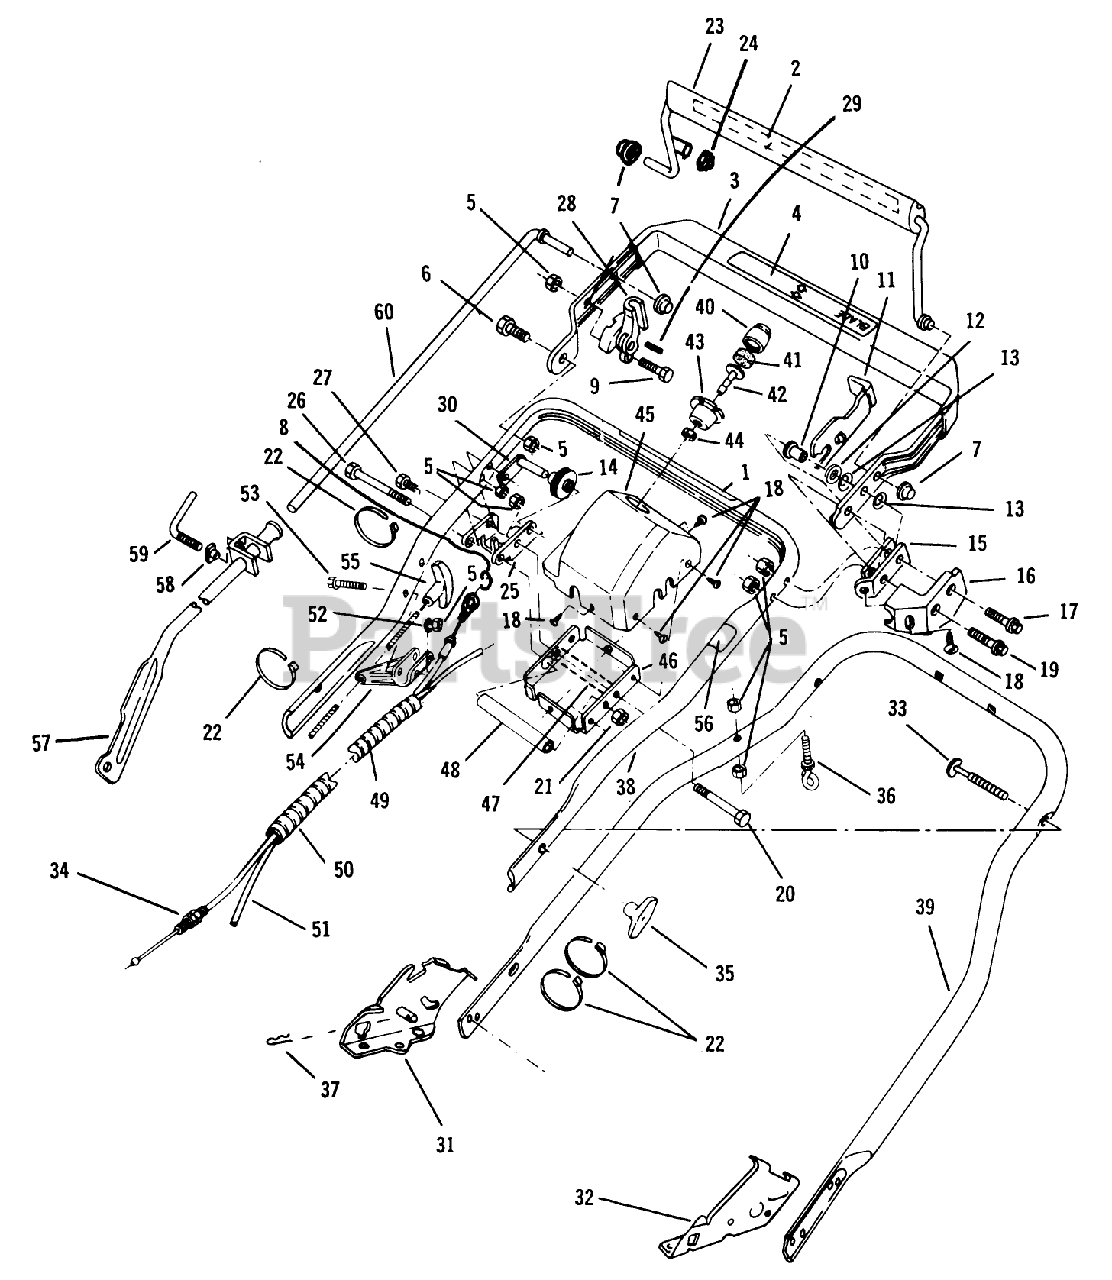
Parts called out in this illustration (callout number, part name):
3	Top Handle and Grip Assembly
5	LOCKNUT E
6	BOLT
8	RET. RING
10	SPACER
12	WASHER M
15	DOWN STOP
16	LOCKOUT GUARD
17	BOLT SHOU
18	SCREW F
19	SCREW
24	NUT ACORN
26	BOLT-CONSOLE
31	BRACKET ASM - HANDLE, SP, RH
32	BRACKET ASM - HANDLE, SP, LH
33	BOLT QUALITY
34	CONTROL CABLE
35	NUT-WING
36	EYE BOLT WAS MFG
37	HAIR PIN
41	FILTER S
44	LOCKNUT S
47	SPACER
52	WASHER
55	HANDLE,STARTER
60	CONTROL ROD
